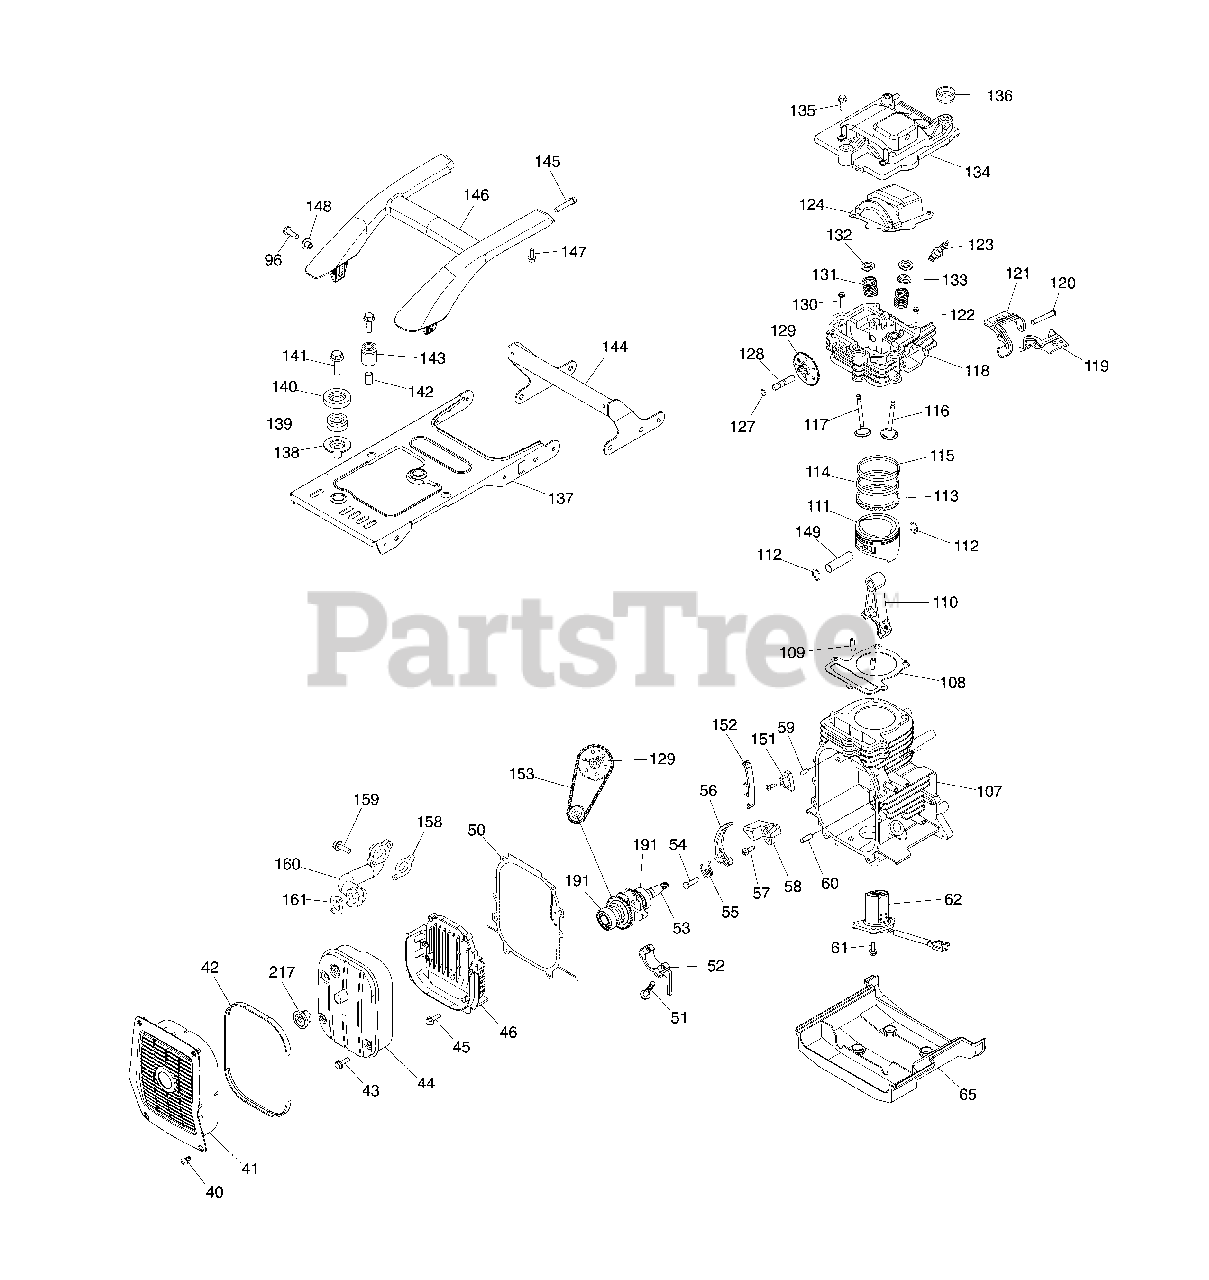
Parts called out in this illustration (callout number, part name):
40	SCREW
43	BOLT-M6 x 75
44	MUFFLER
45	BOLT-M6 x 30
46	COVER-CRANKCASE
50	GASKET-CRANKCASE
51	BOLT-END CAP
52	COVER
53	CRANKSHAFT
54	PIN
55	SPRING
56	ARM-TENSION
57	SCREW
58	BRACKET
59	PIN
60	PIN
61	BOLT-M5 x 14
65	COVER
96	SCREW
107	CRANKCASE
108	GASKET
109	PIN
110	ROD
111	PISTON
112	RETAINER-PIN
113	RING
114	RING
115	RING
116	VALVE-INTAKE
117	VALVE-EXHAUST
118	CYLINDER HEAD
119	ARM-INTAKE VALVE
120	PIN
121	ARM-EXHAUST VALVE
122	BOLT-M8 x 50
124	BLOCK
127	O-RING
128	PIN-SHAFT
129	CAM-ASSEMBLY
130	BOLT-M8 x 70
131	SPRING
132	SEAT-VALVE
133	SEAL-VALVE OIL
134	COVER-CYLINDER
135	BOLT-M6 x 25
136	MOUNT-VIBRATION
138	MOUNT-VIBRATION
139	BUSHING
140	GASKET
141	BOLT-M8 x 30
142	BUSHING
143	MOUNT-VIBRATION
144	MOUNT-VIBRATION
145	BOLT-M5 x 25
147	SCREW
149	PIN-PISTON
151	BRACKET
152	BRACKET
153	CHAIN
159	BOLT-M6 x 20
160	PIPE-MUFFLER
191	BEARING
217	ARRESTOR-SPARK
